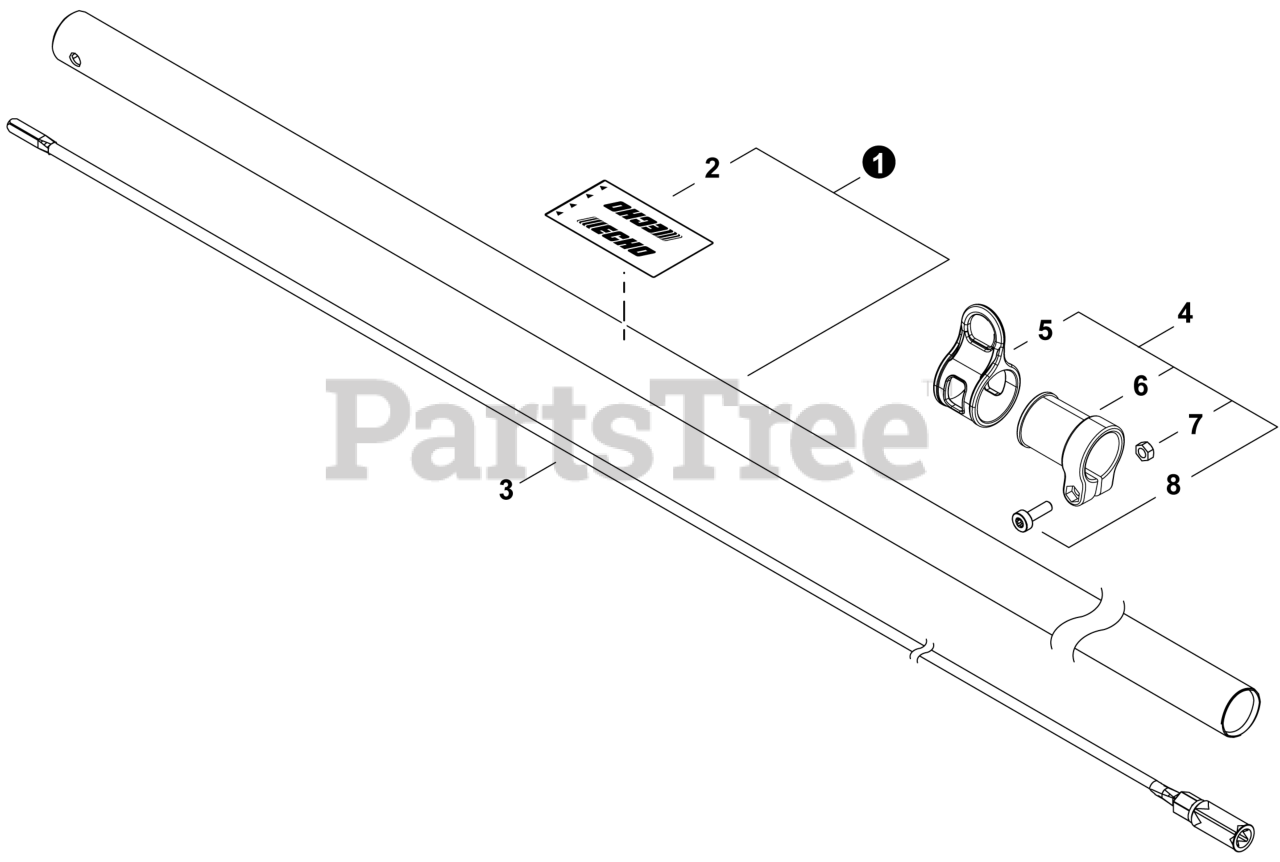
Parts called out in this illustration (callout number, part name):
1	MAIN PIPE ASSY
2	LABEL - HANDLE LOCATION
3	DRIVESHAFT - FLEXIBLE
4	HANGER SET, HARNESS
5	HANGER, HARNESS
6	CUSHION, HANGER
8	BOLT, TORX 5x16
